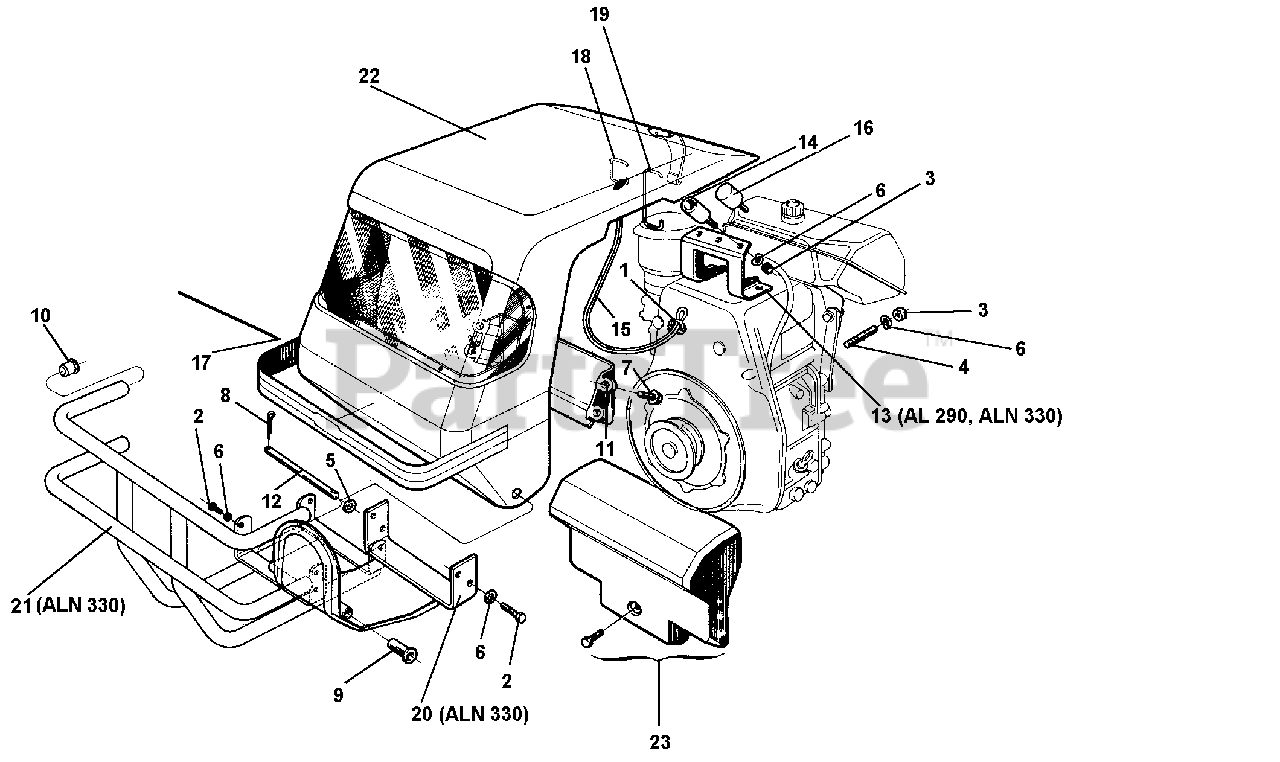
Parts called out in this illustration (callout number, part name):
1	CLAMP, CABLE 3/16
2	SCREW M8 X 16
4	STUD M8 X 40 X 14 X 14
5	FLAT WASHER 10.5 X 21
6	WASHER, LOCK 8.4
7	SCREW AF 6.3 X 16
8	PIN, COTTER A 3 X 20 UNI 1336
11	KIT TOOL BOX
12	PIN, COUPLING
13	COUPLING, TOP, AL290/ALN330WB
14	BUFFER, HOOD COUPLING
15	CABLE, HOOD
17	STRIP SELF-ADHESIVE COVER-735
20	CPLG, LWR MTR AL 290 LA 300
23	FRONT WEIGHT ASBY., (35#)(EA)
